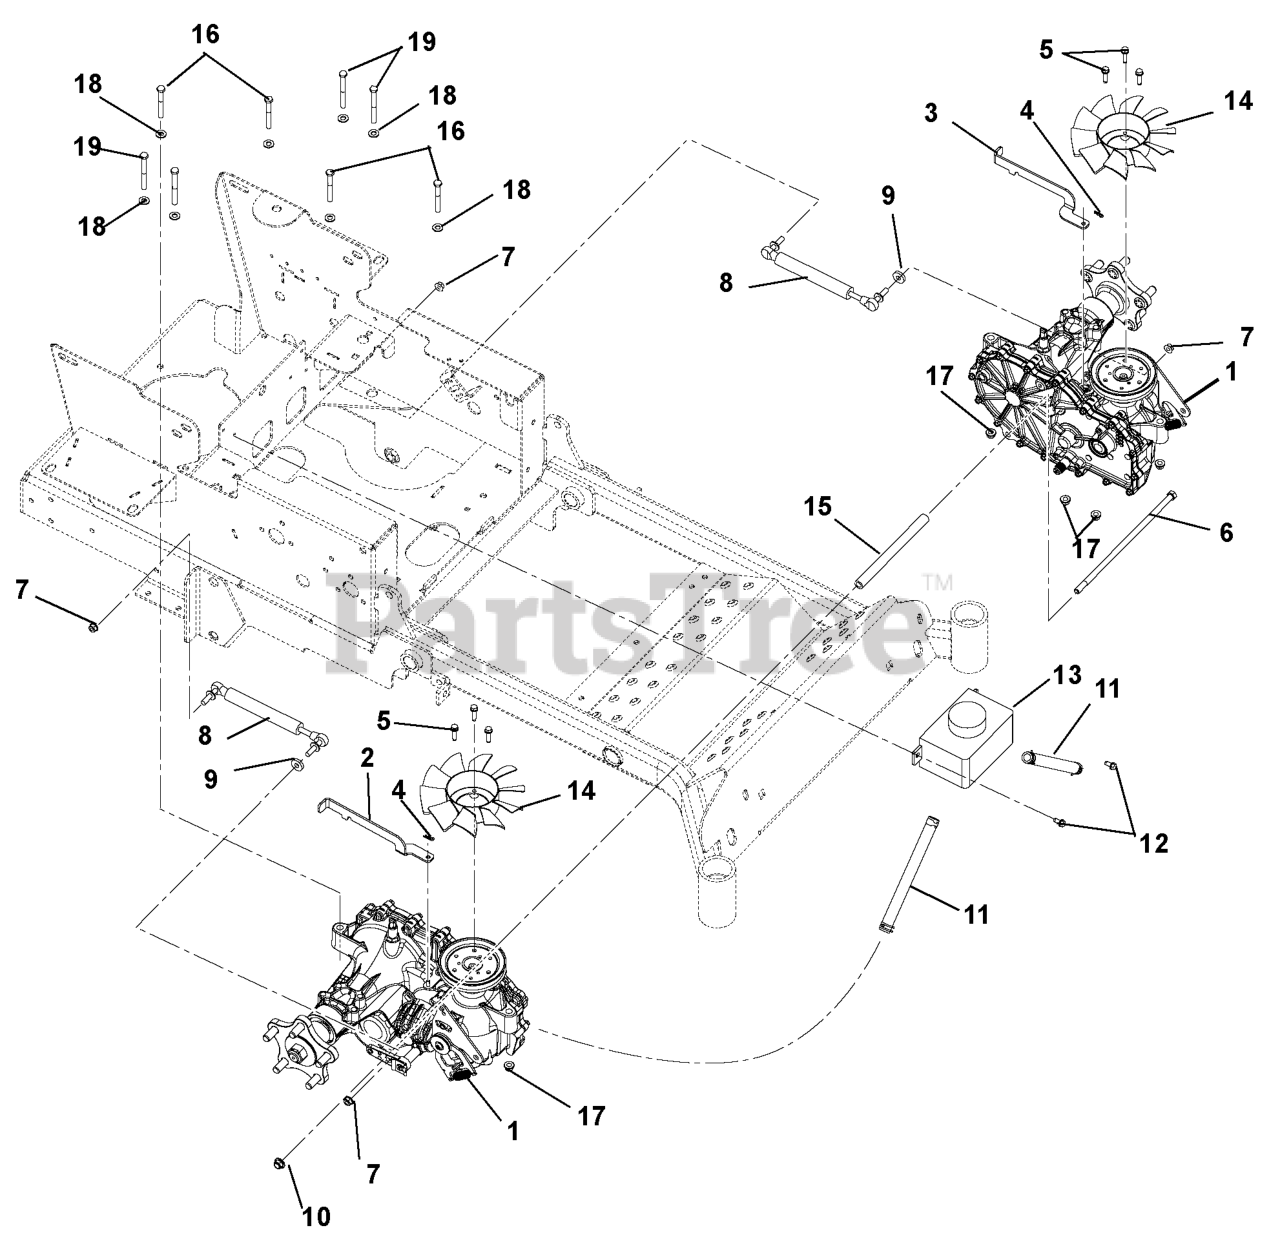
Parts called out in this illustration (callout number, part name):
1	TRANSAXLE, 3100 SERIES - LH
2	RH DUMP VALVE LEVER - BLACK
3	LH DUMP VALVE LEVER - BLACK
4	PIN-HAIR INT .06X.18X.77
5	@SCR-TAP .25-20X1.00 HWH TR YZ
6	BLT HEX, .38-16X11.00 GR5 YWZC
7	NUT, FLG PATCH M8-1.25 BLKZC
9	WSHR-FL-STL .328X.87X.179 YWZC
10	@NUT-LK-NYL-FLG .38-16 YWZC
11	ASM, HYDRO OVERFLOW TANK HOSE
12	@SCR-TAP .25-20X.50 HWH TR YWZ
13	TANK, EXPANSION
14	FAN, 2800 SERIES COOLING
15	SPCR,.406 ID X .630 OD X 7.724
16	@BLT-HEX .31-18X2.50 GR5 YWZC
17	@NUT-LK-NYL-FLG .31-18 YWZC
18	@WSHR-FL-STL.344X.688X.065YWZC
19	@BLT-HEX .31-18X3.00 GR5 YWZC
